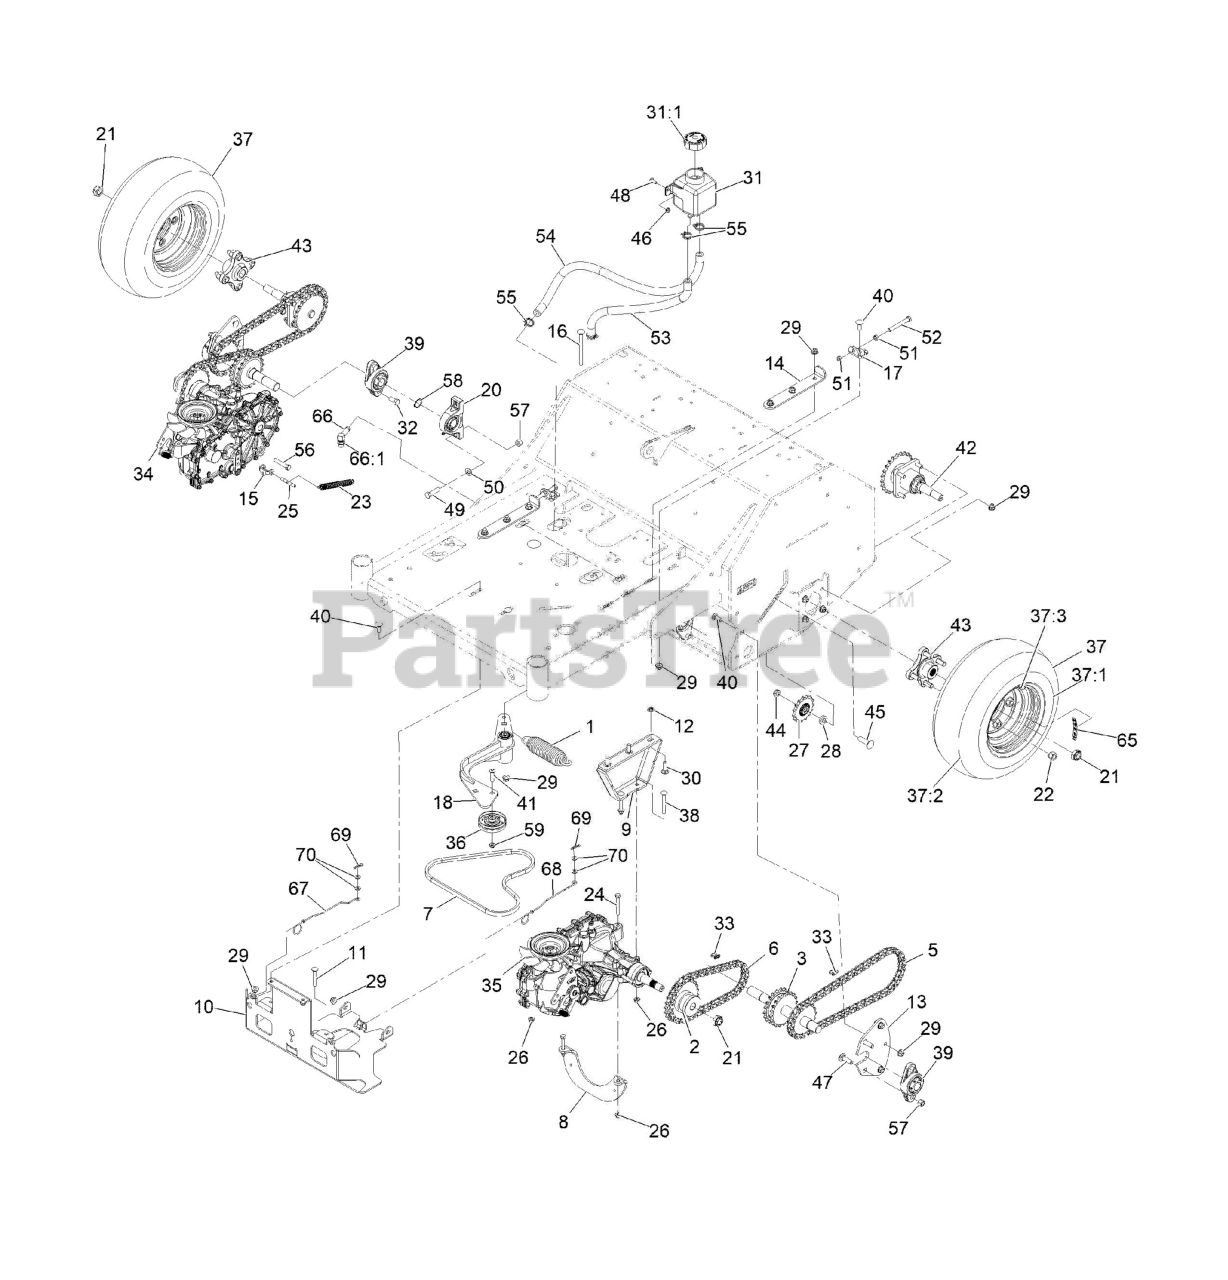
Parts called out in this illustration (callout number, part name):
1	SPRING-EXTENSION
2	HUB-DRIVE, CHAIN
3	JACKSHAFT
5	CHAIN-ROLLER
6	CHAIN-ROLLER
7	BELT-4L SECTION
8	Brace-Angle
9	MOUNT-TRANSMISSION
10	GUARD-TRANSMISSION
11	BOLT-CARR
12	NUT-PUSH
13	Plate-Jackshaft
14	PLATE-ADJUSTMENT, TRANSMI
15	YOKE-BRAKE, PARK
16	BOLT-CARR
17	BRACKET-HYDRO, ADJUST
18	IDLER ARM ASM
20	BEARING-PILLOW BLOCK
21	NUT-LOCK
22	NUT-LUG
23	SPRING-DOOR
24	SCREW-HH
25	PIN-BRAKE, PARK
26	NUT-HF, NI
27	SPROCKET-IDLER, 15T
29	NUT-HF, NI
30	BOLT-CARR
31	TANK-HYD
31:1	CAP-RESERVOIR, HYD
32	SCREW-HH
33	LINK-CONNECTING
34	TRANSAXLE-ZT3100, RT (W/P
35	TRANSAXLE-ZT3100, LT (W/P
36	PULLEY-IDLER
37	Tire ASM (16 X 6.50-8)
37:1	RIM-8X5.375, CENTERED
37:3	Stem-Valve
38	SCREW-CARR
39	BEARING-FLANGE, 2 BOLT
40	BOLT-CARR
41	SCREW-HSBH
42	AXLE AND BEARING ASM
43	HUB-OFFSET
44	NUT-HEX
45	SCREW-CARR
47	BOLT-CARR
48	BOLT-CARR
50	WASHER-FLAT
51	NUT-HEX
52	SCREW-HH
53	HOSE-HYDRAULIC
54	HOSE-HYDRAULIC
55	CLAMP-HOSE
56	SCREW-HH
57	NUT-LOCK, NI
58	RING-RETAINING
65	DECAL-HUB, WHEEL
66	FITTING-ELBOW, 90
66:1	O-RING
67	ROD-BYPASS, RH
68	ROD-BYPASS, LH
69	PIN-COTTER
